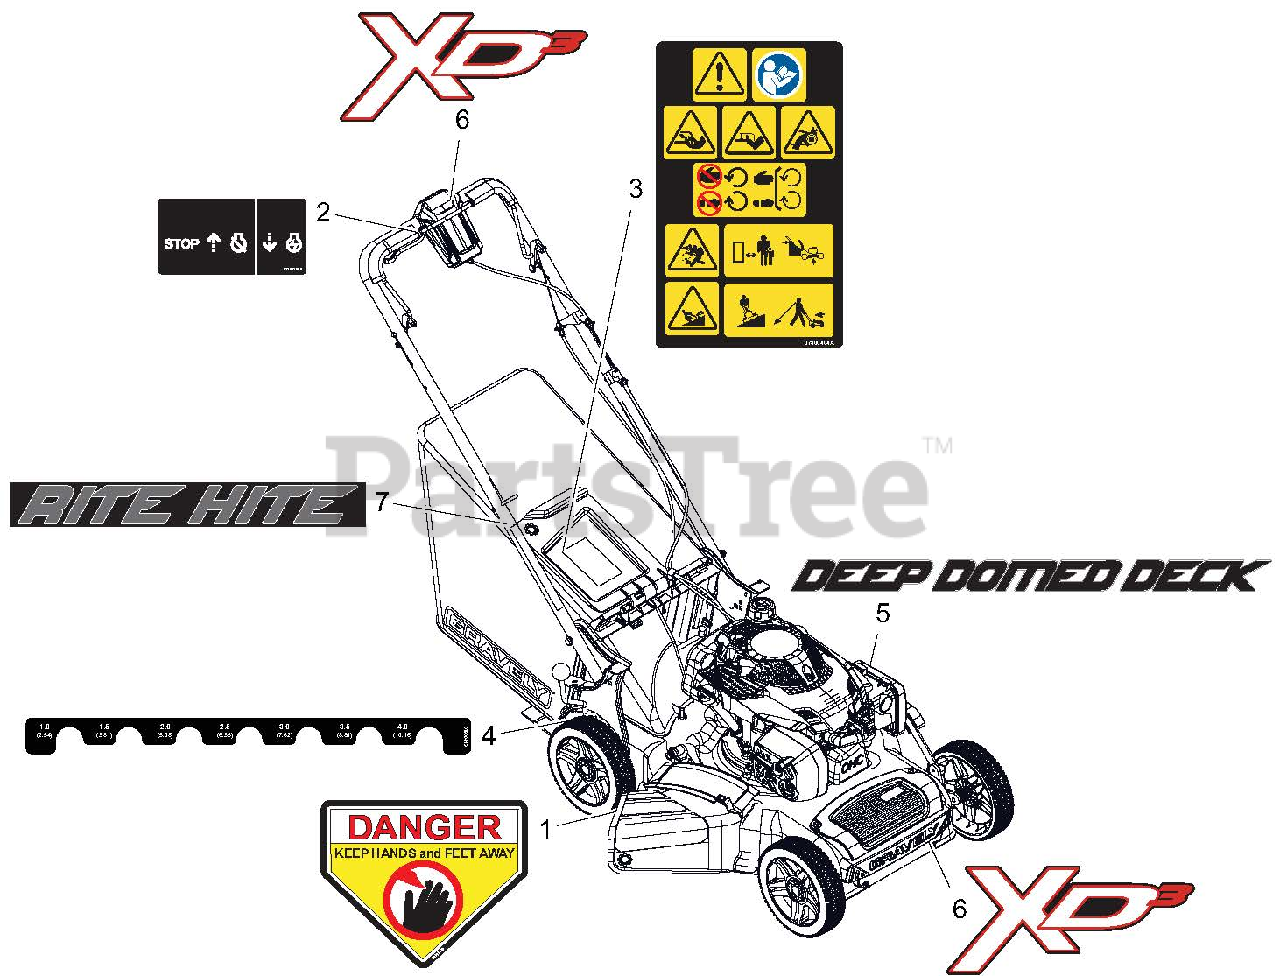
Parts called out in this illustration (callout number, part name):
1	DECAL, DANGER
2	DECAL, ENGINE CONTROL
3	DECAL, MAIN SAFETY WAW LM
4	DECAL, HOC
5	DECAL, DEEP DOME DECK
6	DECAL, GRAVELY XD3 STYLE
7	DECAL, RITE HITE
